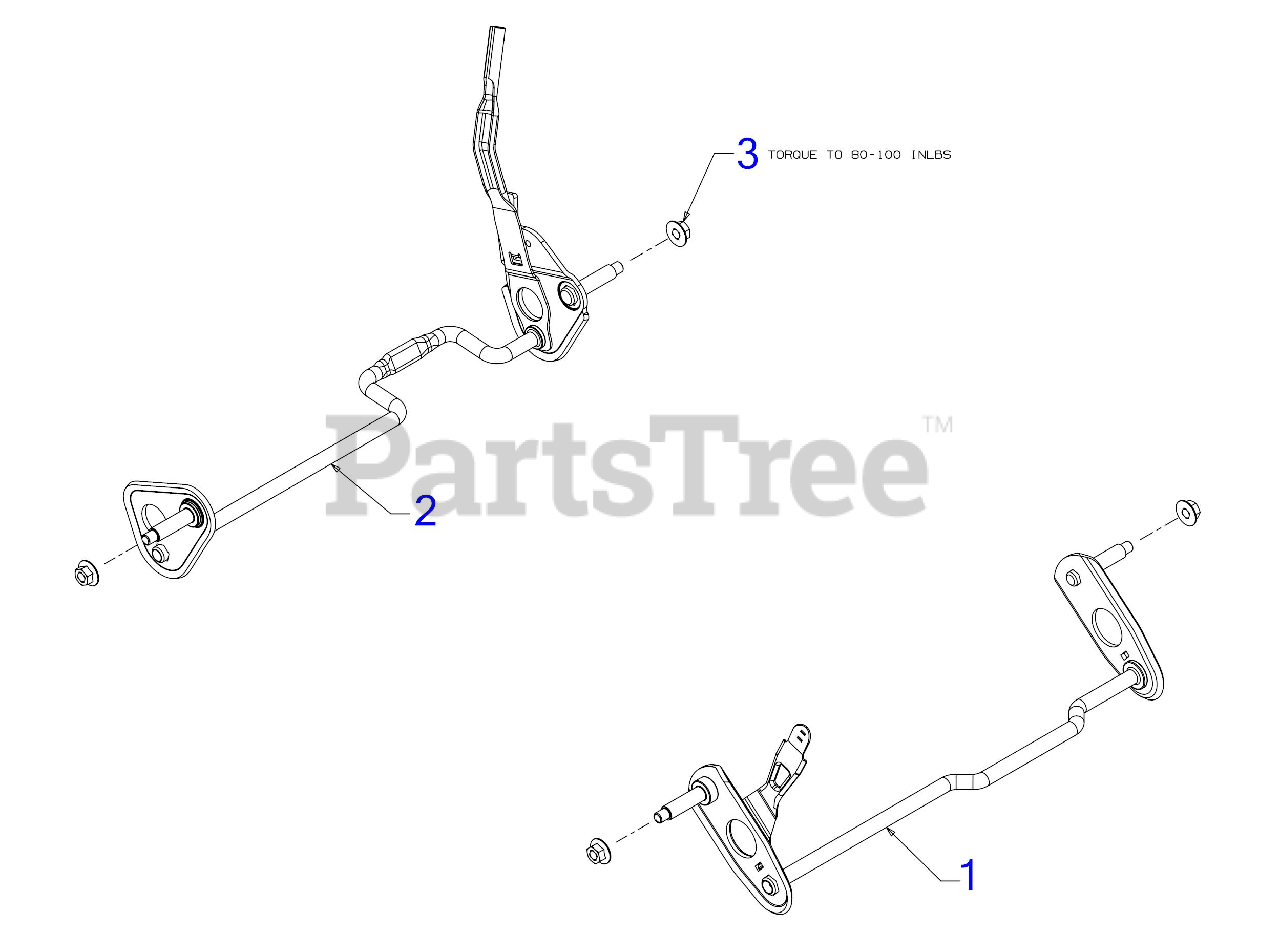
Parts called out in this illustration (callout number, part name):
1	8" FRONT AXLE ASSEMBLY
2	HEIGHT AXLE ASSEMBLY
3	FLANGE LOCK NUT
